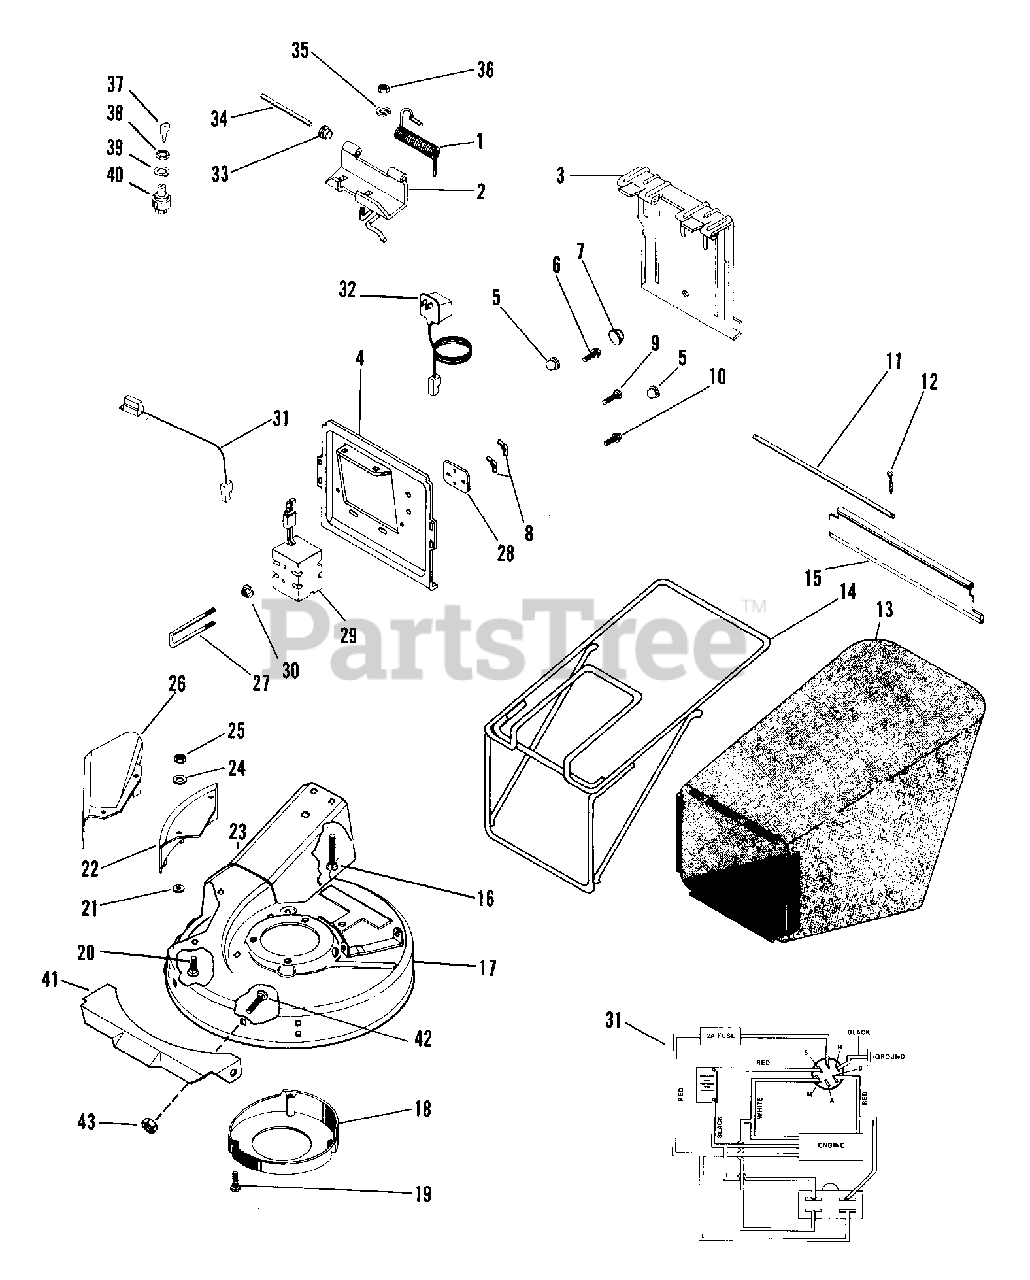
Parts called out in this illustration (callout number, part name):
1	SG-TORS .120X.68X3.09
1	SG-TORS .062X.28X1.00
2	HINGE BASE
2	HINGE PLATE WLDMT FOREIGN ELEC
2	HINGE BASE WELDMENT
3	CATCHER PLATE DOOR
4	CATCHER PLATE
6	SCR-TAP 10-24X.375 TORX PHD
7	BUTTON BUMPER
8	NUT-WING 8-32
9	@BLT-RHDSSQNK .25-20X.38 G2YZ
10	SCR-TAP 12-24X.50 HWH PL TR
11	ROD
12	PIN-COTR .06X.50
13	BAG,CONSUMER BLACK 15 OZ/YD2
13	BAG,COMMERCIAL WHITE
14	BAGGER FRAME
15	REAR PROTECTIVE GUARD
15	REAR PROTECTIVE GUARD, PUSH
15	REAR PROTECTIVE GUARD, S.P.
16	BLT-RDHDSQNK .25-20X.62 PL
17	MOWER PAN W/DECALS
18	CENTER BAFFLE
19	SCR-TAP 10-16X.62 SLPH PL AB
20	BLT-RDHDSQNK .31-18X.75 SHT PL
21	NUT-PUSH .312
22	SIDE DISCHARGE COVER
23	PLASTIC GROMMET
24	WSHR-FL-STL .38X.875X.083 PL
25	NUT-LK-NYL.312-18 PL
26	DISCHARGE CHUTE
27	U-BOLT
28	BATTERY PLATE
29	BATTERY
29	BATTERY,12 VOLT 2.5 AH
30	NUT-LK-FLG .250-20 PL
31	POWER CORD
31	WIRE HARNESS, FOREIGN
31	WIRE HARNESS
32	CAM BRACKET RH
32	SIDE DISCHARGE COVER
33	PUSH NUT, .25
34	DOOR PIN
35	WSHR-LK .250X.077 HVY PL
36	NUT-HEX .250-20 PL
37	KEYS - WITH RING
37	KEYS
38	NUT .812-20 PL
38	NUT .625-32 ALUM
39	WSHR-LK-INT .813X.020 PL
39	WSHR-LK-INT .625X.045 PL
40	KEY SWITCH ASSEMBLY
40	KEY SWITCH
41	FRONT PANEL
42	BLT-RDHDSQSHNK .31-18X.50 YZ
43	NUT-LK .312-18 GR A PL
